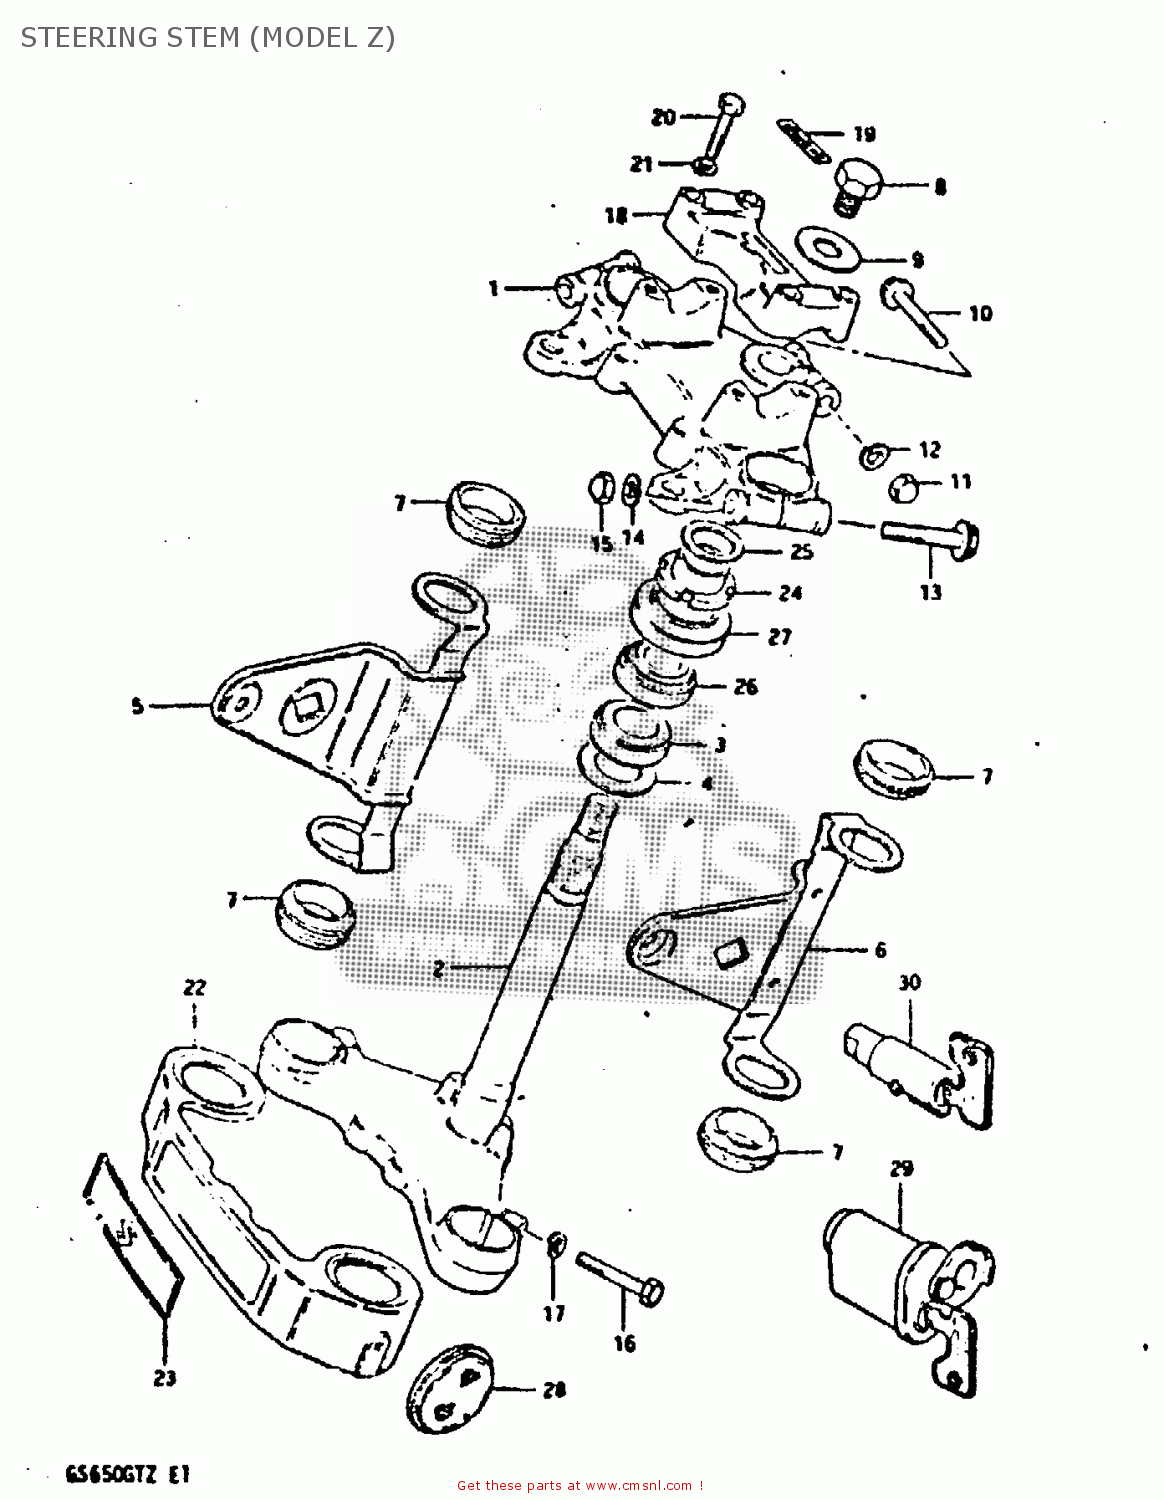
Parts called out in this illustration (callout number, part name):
1	STEM HEAD, STEERING (BLACK)
2	STEM, STEERING
3	BEARING
4	WASHER,THRUST
5	BRACKET,HEADLAMP,RIGHT
6	BRACKET,HEADLAMP,LEFT
7	CUSHION,HEADLAMP BRACKET
8	BOLT(12X20)
9	WASHER
10	BOLT
11	NUT,M8X1.25X12
12	LOCK WASHER
13	BOLT 10X55
14	LOCK WASHER
15	NUT
16	BOLT 10X40
17	LOCK WASHER
18	HOLDER,HANDLEBAR
19	EMBLEM,HANDLE CLAMP
20	BOLT
21	LOCK WASHER
22	COVER,FRONT FORK
23	EMBLEM
24	NUT,STEERING STEM
25	WASHER(18.5X24X1)
26	TAPER,ROLLER BEARING
27	DUST SEAL,STEERING UPR
28	REFLEX REFLECTOR, FRONT
